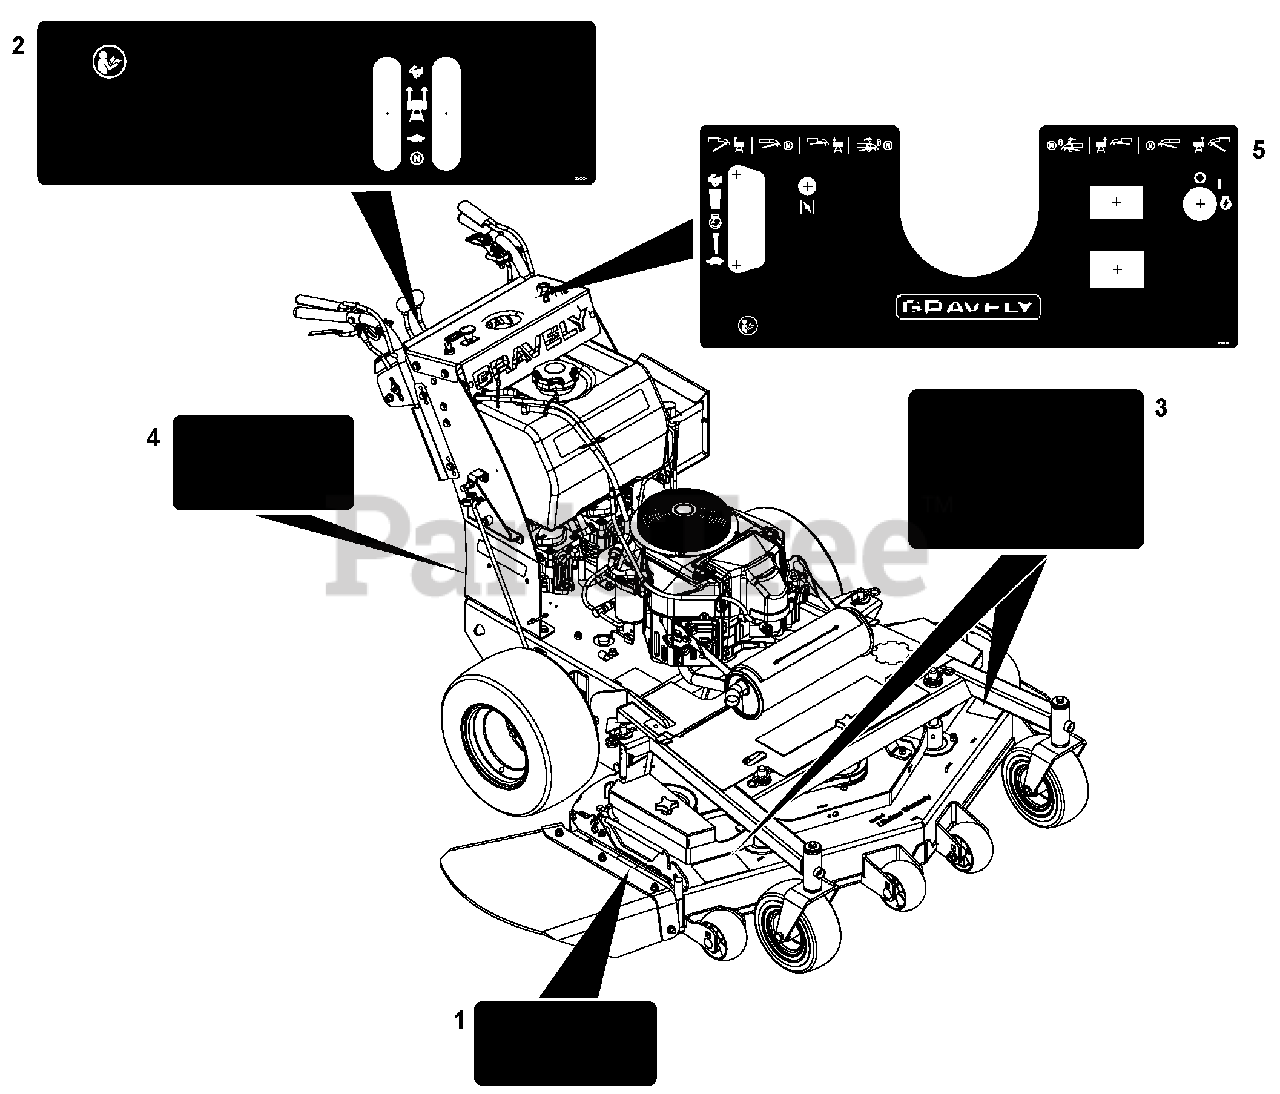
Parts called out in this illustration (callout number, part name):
1	Decal, Warning (SN 000101 - 020000)
2	Decal, Gravely PG Control (SN 000101 - 020000) (988153, 154, 155)
3	Decal, Mower Pan Danger (SN 000101 - 020000) (988153, 156)
4	Decal, Danger Belt Rotation (SN 000101 - 020000)
5	Decal, Gravely Console (SN 000101 - 020000) (988153, 154, 155)
